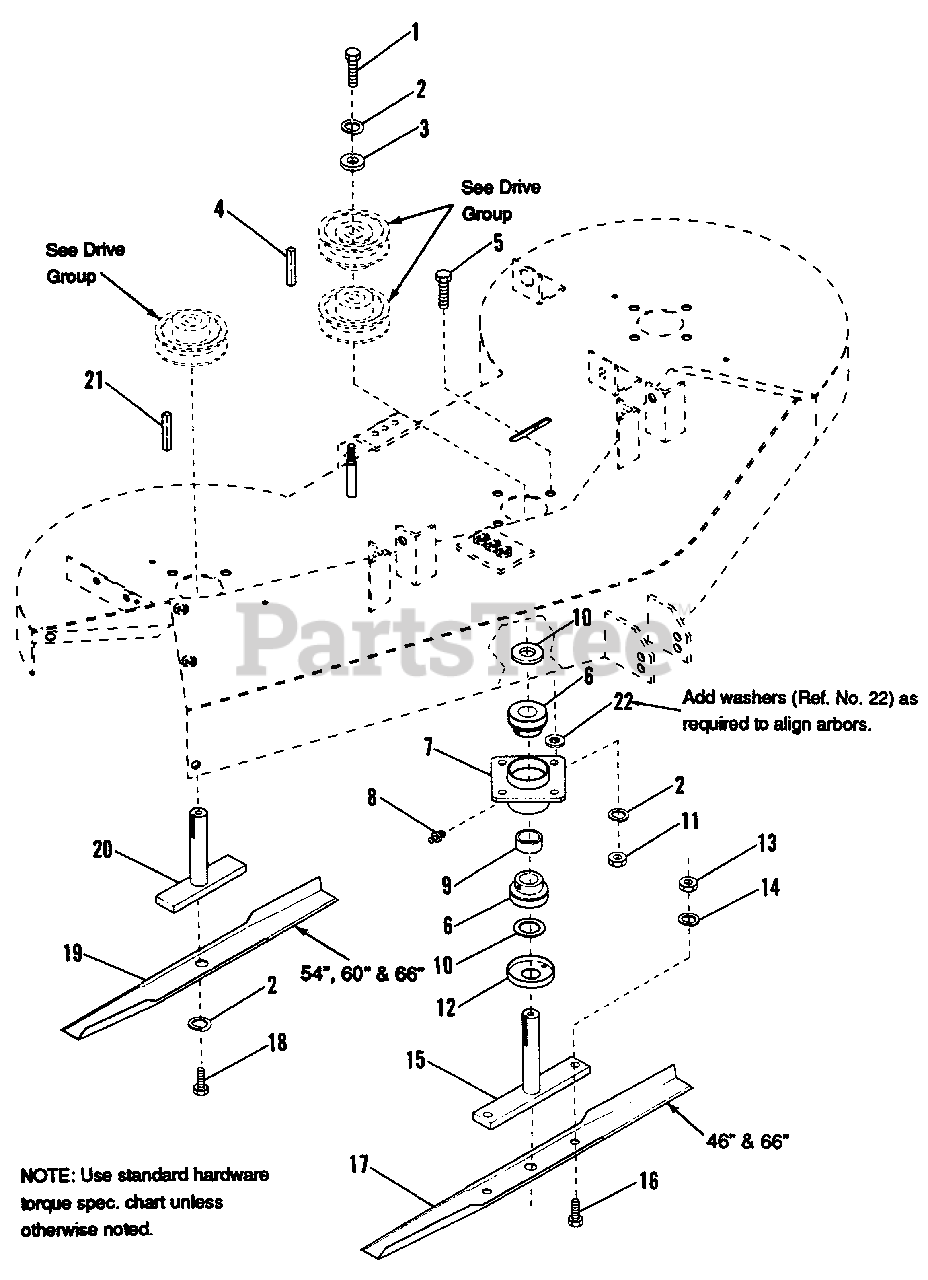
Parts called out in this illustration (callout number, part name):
1	CAPSCREW, Hex 3/8-24 x 1 (1691847)
1	CAPSCREW, Hex 3/8-24 x 1 (1691847) CAPSCREW, Hex 3/8-24 x 1 (1691848 to 1691850)
2	LOCKWASHER, Spring 3/8 (1691847)
2	LOCKWASHER, Spring 3/8 (1691847) LOCKWASHER, Spring 3/8 (1691848, 1691849)
2	LOCKWASHER, Spring 3/8 (1691847) LOCKWASHER, Spring 3/8 (1691848, 1691849) LOCKWASHER, Spring 3/8 (1681850)
3	WASHER, Plain (1691847)
3	WASHER, Plain (1691847) WASHER, Plain (1691848 to 1691850)
4	KEY, Square 1/4 x 1/4 x 1-3/4
5	CAPSCREW, Hex 3/8-16 x 1-1/4 (1691847)
5	CAPSCREW, Hex 3/8-16 x 1-1/4 (1691847) CAPSCREW, Hex 3/8-16 x 1-1/4 (1691848 to 1691850)
6	BEARING, Ball (1691847)
6	BEARING, Ball (1691847) BEARING, Ball (1691848 to 1691850)
7	HOUSING ASSY., Arbor (1691847)
7	HOUSING ASSY., Arbor (1691847) HOUSING ASSY., Arbor (1691848 to 1691850)
8	FITTING, Grease (Press Fit)(1691847)
8	FITTING, Grease (Press Fit)(1691847) FITTING, Grease (Press Fit)(1691848 to 1691850)
9	SPACER, Bearing (1691847)
9	SPACER, Bearing (1691847) SPACER, Bearing (1691848 to 1691850)
10	WASHER, Plain (1691847)
10	WASHER, Plain (1691847) WASHER, Plain (1691848 to 1691850)
11	NUT, Hex 3/8-16 (1691847)
11	NUT, Hex 3/8-16 (1691847) NUT, Hex 3/8-16 (1691848-1691850)
12	CUP (1691847)
12	CUP (1691847) CUP (1691848 to 1691850)
13	NUT, Hex 1/2-13 (1691847, 1691850)
14	LOCKWASHER, Spring 1/2 (1691847, 1691850)
15	ARBOR ASSY., Long (1691847, 1691850)
15	ARBOR ASSY., Long (1691848, 1691849)
16	CAPSCREW, Hex 1/2-13 x 1-1/4 (1691847, 1691850)
17	BLADE, Mower, (1691847, 1691850)
18	CAPSCREW, Hex 3/8-16 x 1 (1691847)
18	CAPSCREW, Hex 3/8-16 x 1 (1691847) CAPSCREW, Hex 3/8-16 x 1 (1691848, 1691849)
18	CAPSCREW, Hex 3/8-16 x 1 (1691847) CAPSCREW, Hex 3/8-16 x 1 (1691848, 1691849) CAPSCREW, Hex 3/8-16 x 1 (1691850)
19	BLADE, Mower (1691848)
19	BLADE, Mower (1691847)
19	BLADE, Mower (1691847) BLADE, Mower (1691849)
19	BLADE, Mower (1691847) BLADE, Mower (1691849) BLADE, Mower (1691850)
20	ARBOR ASSY., Short (1691847)
20	ARBOR ASSY., Short (1691847) ARBOR ASSY., Short (1691848 to 1691850)
21	KEY, Square 1/4 x 1/4 x 1 (1691847)
21	KEY, Square 1/4 x 1/4 x 1 (1691847) KEY, Square 1/4 x 1/4 x 1 (1691848 to 1691850)
22	WASHER, Plain (1691847)
22	WASHER, Plain (1691847) WASHER, Plain (1691848 to 1691850)
